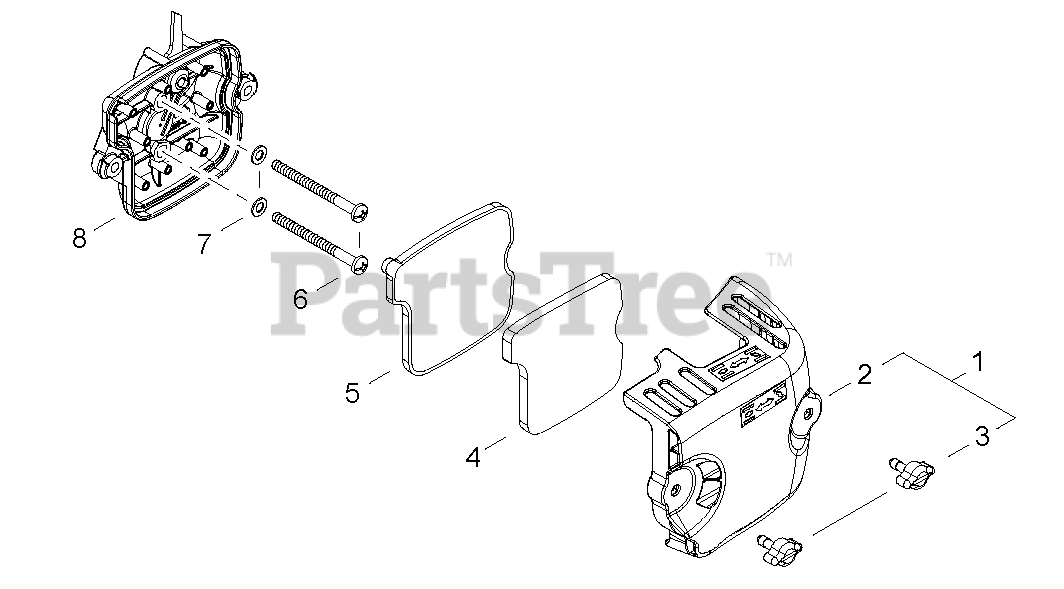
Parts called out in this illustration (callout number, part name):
1	AIR FILTER COVER ASSY
2	COVER, AIR FILTER
3	THUMBSCREW
4	PRE-FILTER, FOAM
5	FILTER, AIR
6	SCREW - 5X60
7	WASHER - 5
8	AIR FILTER CASE ASSY
